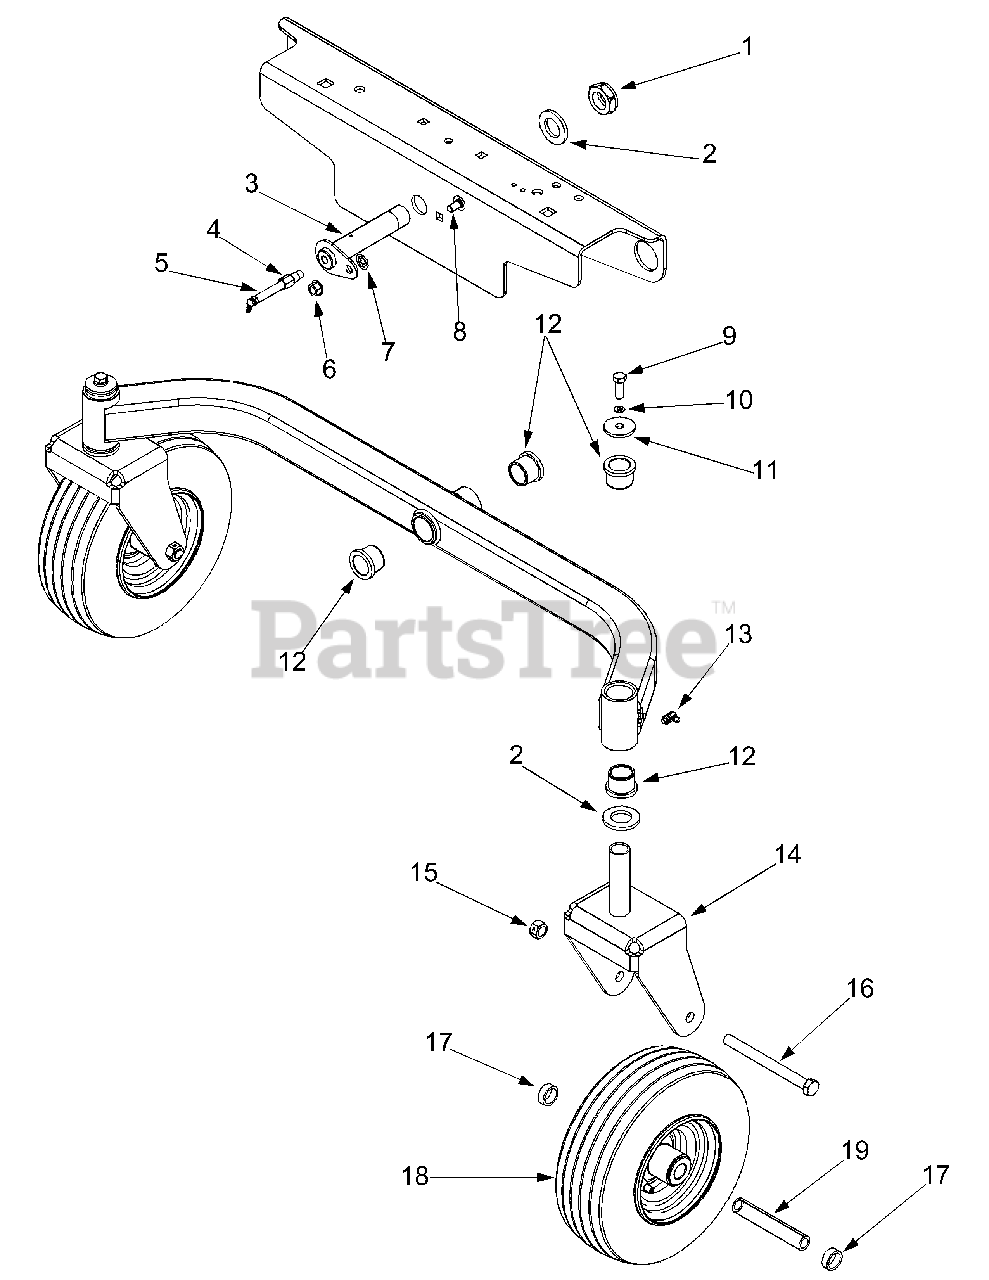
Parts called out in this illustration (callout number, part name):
1	Hex Lock Nut, 1.0-14
3	Pin Ass’y, Pivot
4	Adapter, 1/8 NPTF x 1/8 NPTF
5	Grease Fitting, 65° w/Extension
6	Hex Flange Lock Nut, 3/8-16
7	Push Nut, 3/8 ID
8	Carriage Bolt, 3/8-16 x .75
9	Hex Cap Screw, 3/8-16 x 1.0
10	Lock Washer 3/8
11	Hex Center Lock Nut, 1/2-20
12	Flange Bearing 1.0 ID
13	Grease Fitting
15	Hex Center Lock Nut 1/2-20
16	Hex Cap Screw, 1/2-20 x 5.5
17	Spacer, .79 ID x .347 Lg ‘
18	Wheel Comp 11.0 x 4.0 x 5.0
19	Wheel Spacer
